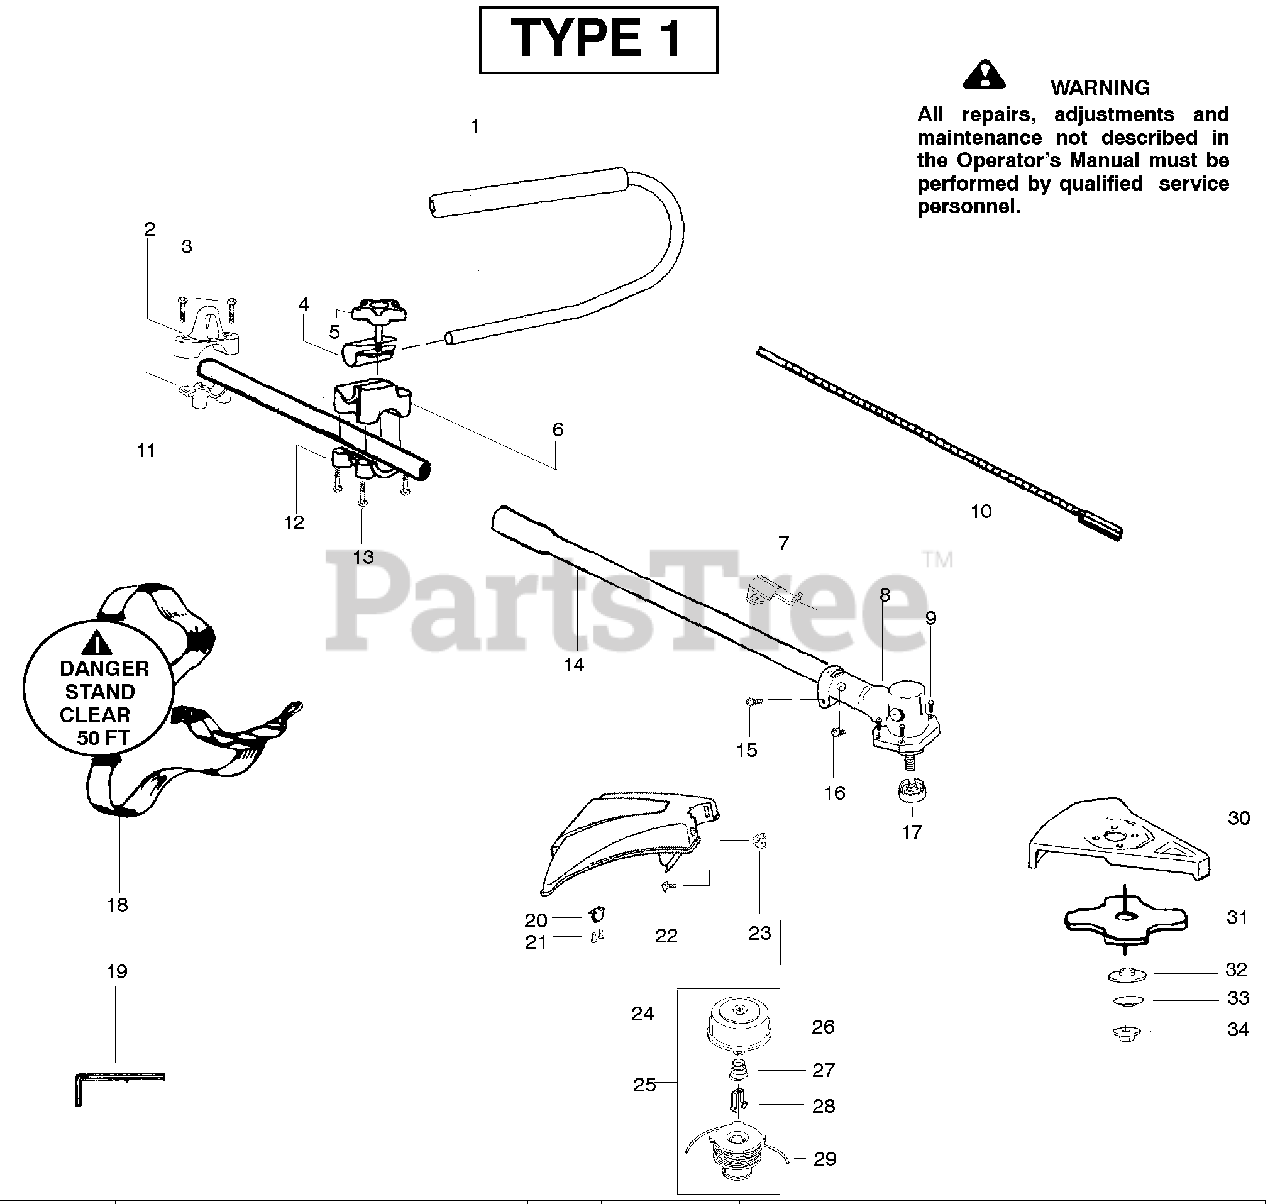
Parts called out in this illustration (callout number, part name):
1	Kit-Handlebar
2	Clamp-Harness Upper
4	Clamp-Handlebar
5	Knob
6	Base-Clamp
7	Bracket-Shield
10	Flexshaft-Split boom
11	Clamp-Harness Lower
12	Kit-Clamp-Tube
14	Assy.-Driveshaft
16	Screw-Alignment
17	Dust cup - Blade
18	Assy-Shoulder Strap
19	Wrench-Hex (5/32")
21	Screw
23	Wingnut
24	Kit-Shield
25	Accy-Cutting Head
29	Accy-Spool
30	Kit-Blade Shield
31	Accy.-Weed Blade (8")
32	Washer-Blade Retaining
33	Washer-Belleville
